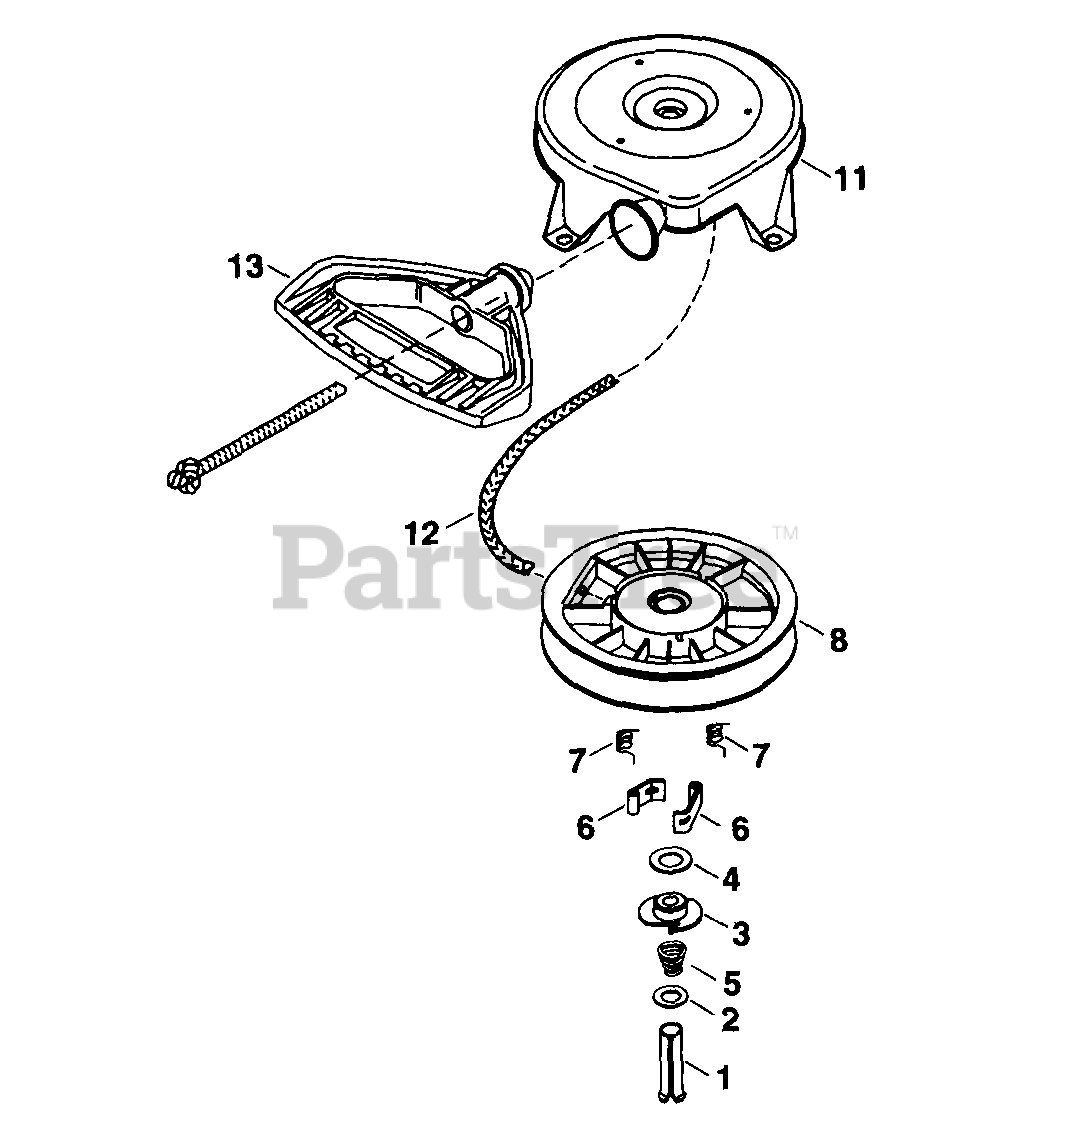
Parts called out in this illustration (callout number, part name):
1	Pin, Spring
5	Spring, Brake
6	Dog, Starter
7	Spring, Dog
8	Pulley & Rewind Spring Ass'y.
11	Housing Ass'y., Starter
12	Rope, Starter (Length 114" & 11/64" Dia.)
13	Handle, Mitten Grip
